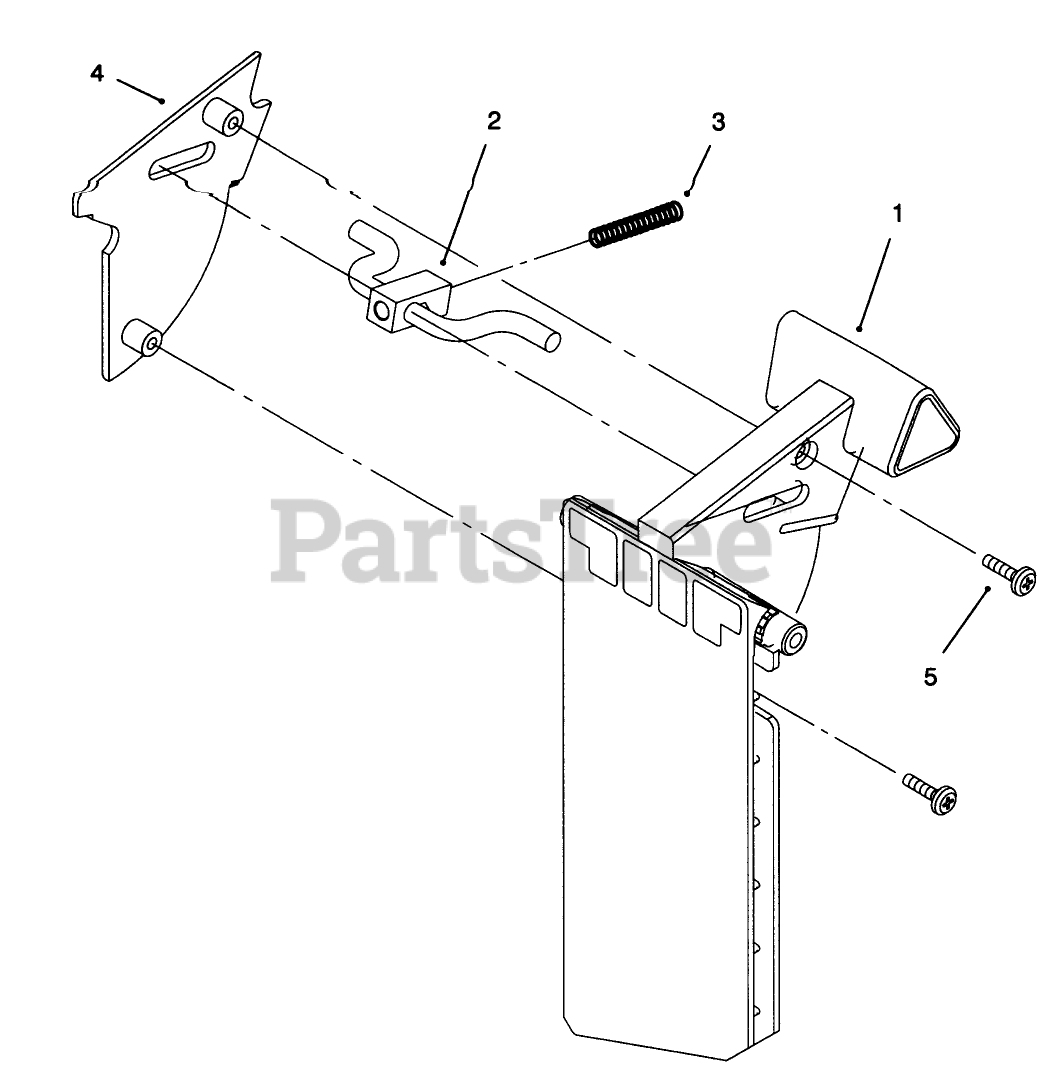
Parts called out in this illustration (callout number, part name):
1	DOOR-DISCHARGE
2	LATCH-DOOR
3	SPRING-COMPRESSION, LATCH
4	DOOR COVER
